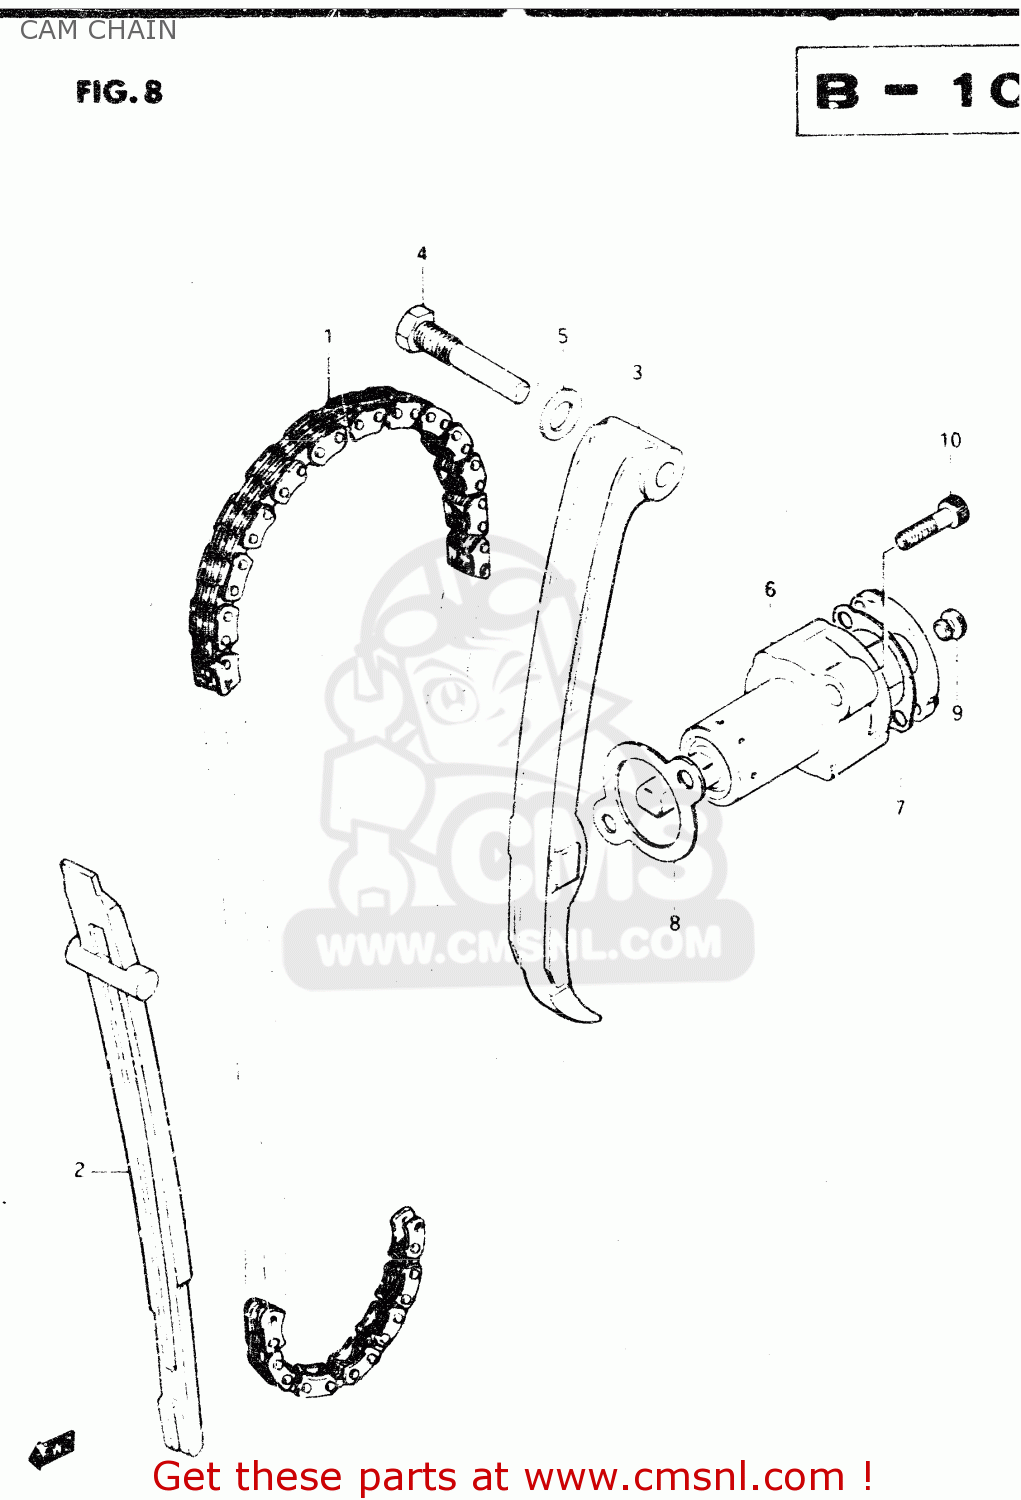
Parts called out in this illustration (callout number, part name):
1	CHAIN,CAMSHAFT DRIVE
2	GUIDE,CAM CHAIN
3	TENSIONER,CAM CHAIN
4	BOLT,CAM CHAIN TENSIONER
5	GASKET 8.2X14X1 (NAS)
6	ADJUSTER ASSEMBLY,TENSIONER
7	GASKET,ADJUSTER CAP (MCA)
8	GASKET,TENSIONER ADJUSTER (MCA)
9	PLUG,ADJUSTER
10	BOLT
